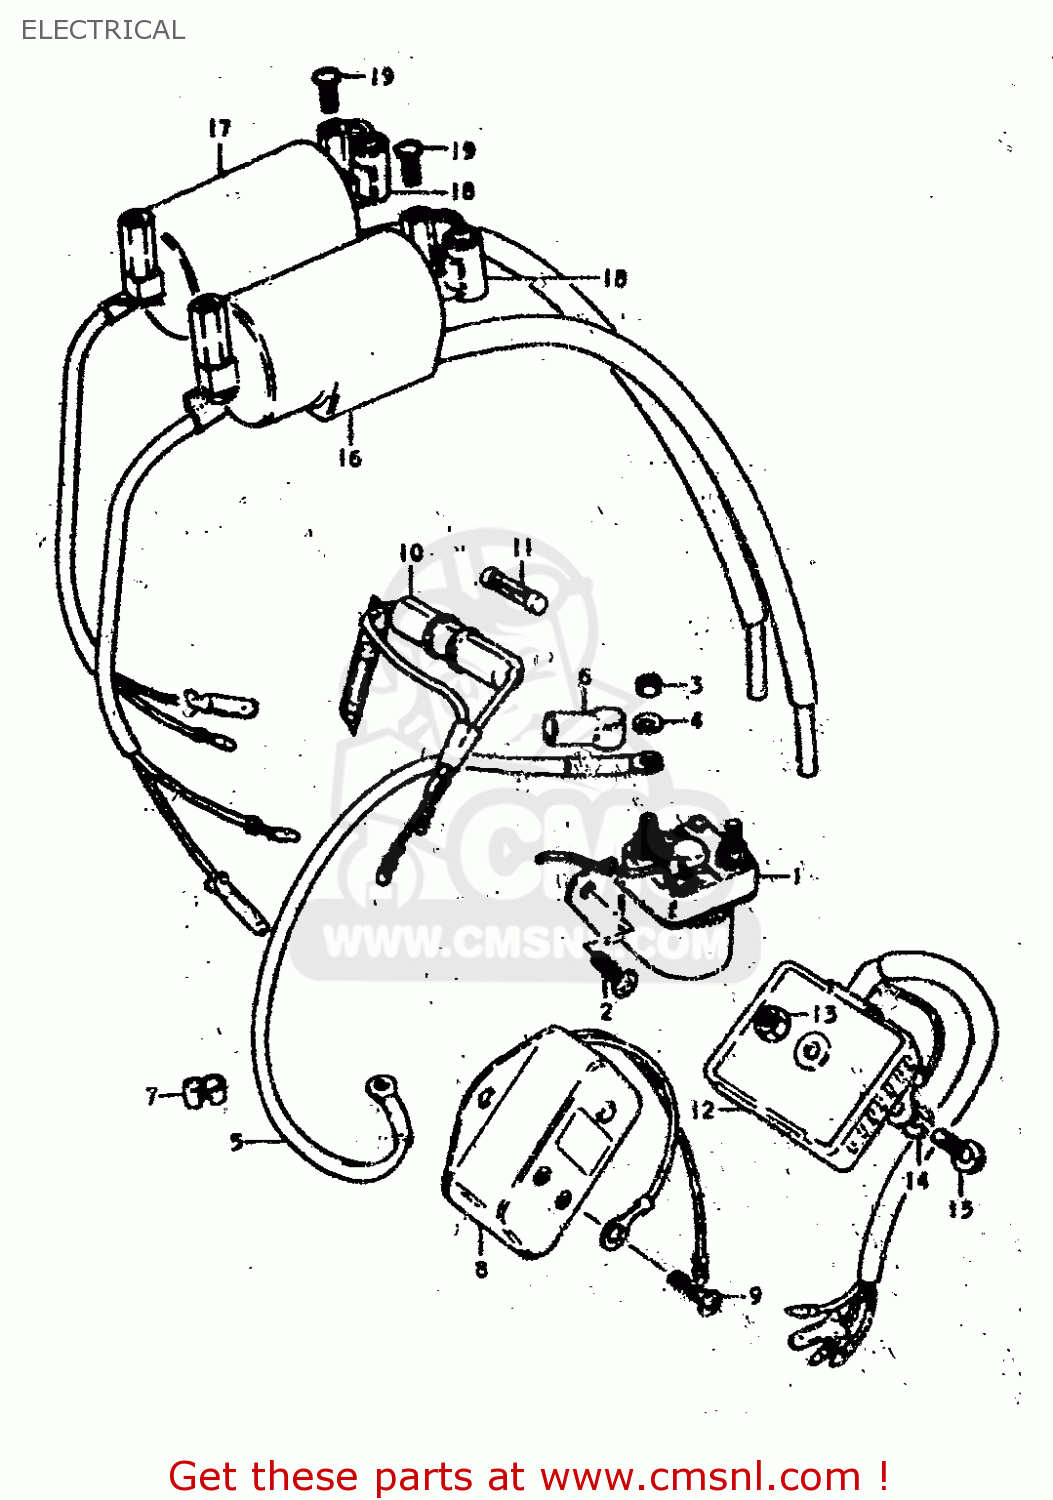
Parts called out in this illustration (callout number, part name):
1	RELAY ASSY,STARTING MOTOR
2	SCREW
3	NUT 6MM
4	LOCK WASHER
5	WIRE,STARTER MOTOR LEAD
6	CAP,STARTER RELAY
7	CLIP
8	REGULATOR ASSEMBLY
9	SCREW
10	BOX ASSEMBLY,FUSE
11	FUSE(15A)
12	RECTIFIER ASSY
14	LOCK WASHER
15	SCREW
16	COIL ASSEMBLY,IGNITION
17	COIL ASSEMBLY,IGNITION
18	CONDENSER
19	SCREW
